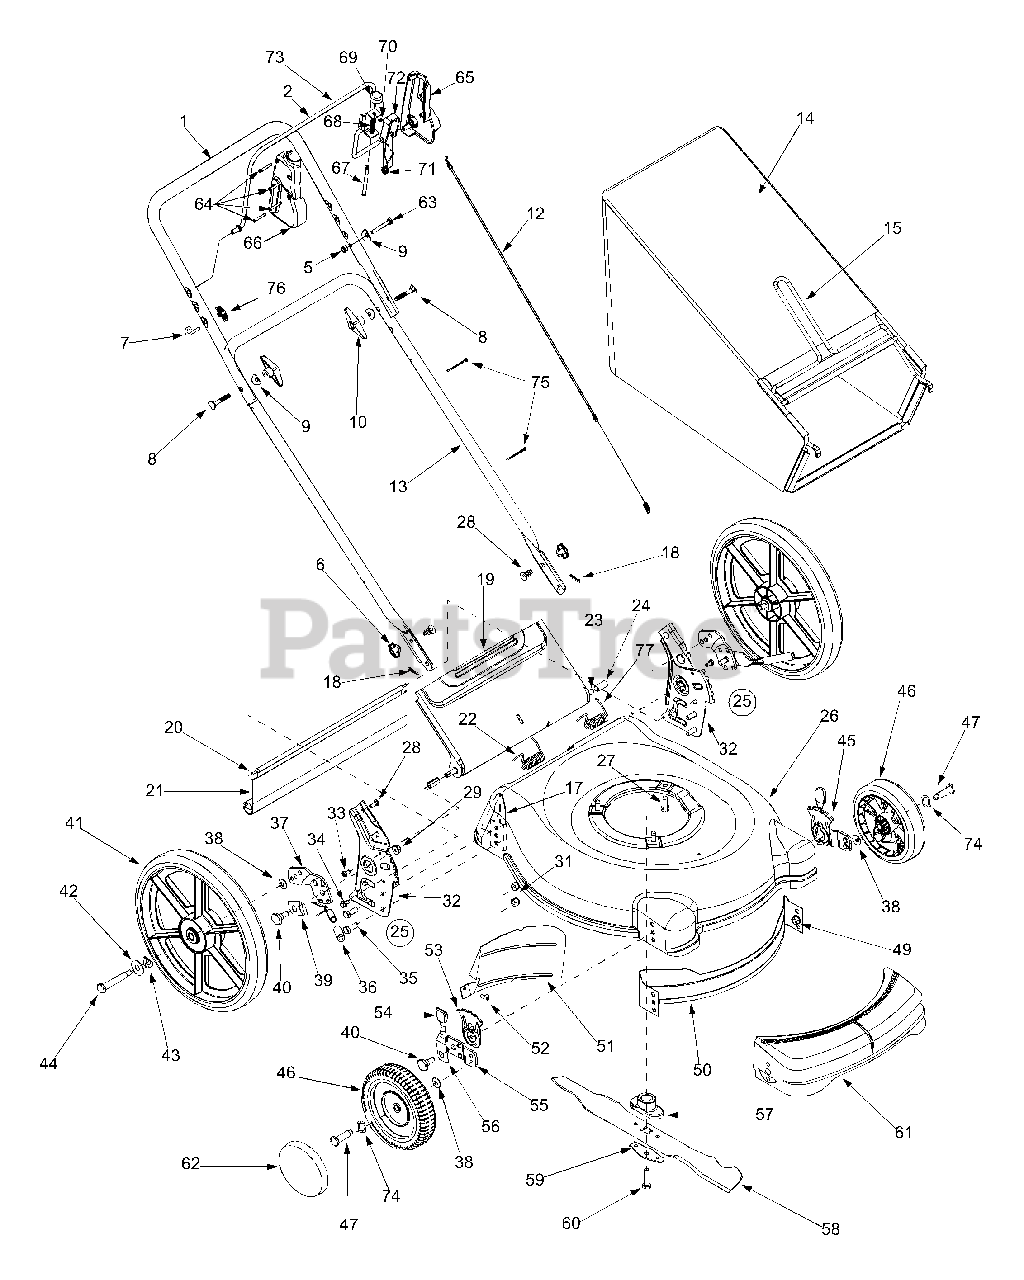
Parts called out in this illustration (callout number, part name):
6	Wing Nut
7	Rope Guide
8	Carriage Bolt 5/16-18 x 2"
9	Shoulder Washer.320 ID x.930 OD
10	Wing Nut
12	Self Start Control Cable 58.25"
14	Grass Bag
18	Hairpin Clip
19	Grass Bag Door
20	Wire Rod
21	Trail Shield
22	Door Spring R.H.
23	Chute Door Pivot Rod
24	Spacer.375 O.D. X.50 I.D. X. 1.02"
25	Handle Bracket Assy. Complete - LH
27	Hex Washer Screw 3/8-16 x 1.0
28	Hex Carriage Screw 1/4-20
29	Flange Lock Nut 3/8-16
31	Flange Lock Nut 3/8-16
32	Handle Bracket Assembly - RH
33	Machine Screw 1/4-20 x.500
34	Hex Washer Screw 1/4-14 x.625
35	Hex Cap Screw 3/8-16 x.75
36	Foam Grip
37	Pivot Bar - RH
38	Spring Washer.375 ID x.870 OD
39	Spring Lever
40	Shoulder Screw
41	Rear Wheel Assembly 14 x 2.1
42	Flat Washer .510 ID x 1.00 OD
43	Wave Washer .500 ID x 1.0 OD
44	Shoulder Screw
45	Front Height Adjuster - RH
46	Front Wheel Assembly 8 x 2.1
47	Shoulder Bolt
49	Flange Lock Nut 3/8-16
52	Tap Screw 1/4-14 x.625.
53	Height Adjustment Plate
54	Height Adjustment Knob
56	Spring Lever
57	Blade Adapter
58	21" Mulching Blade
59	Blade Bell Support
60	Hex Cap Screw 3/8-24 x 1.5
61	Front End Cover
62	Hub Cap
63	Hex Hd. Cap Scr. 1/4-20 Gr.5
64	Hi-Low Screw
65	Control Cover LH
66	Control Cover RH
68	Compression Spring
69	Button
70	Retention Spring
71	Torsion Spring
72	Lever
74	Wave Washer.510 x.750
75	Cable Tie
76	Wing Nut
77	Door Spring L.H.
